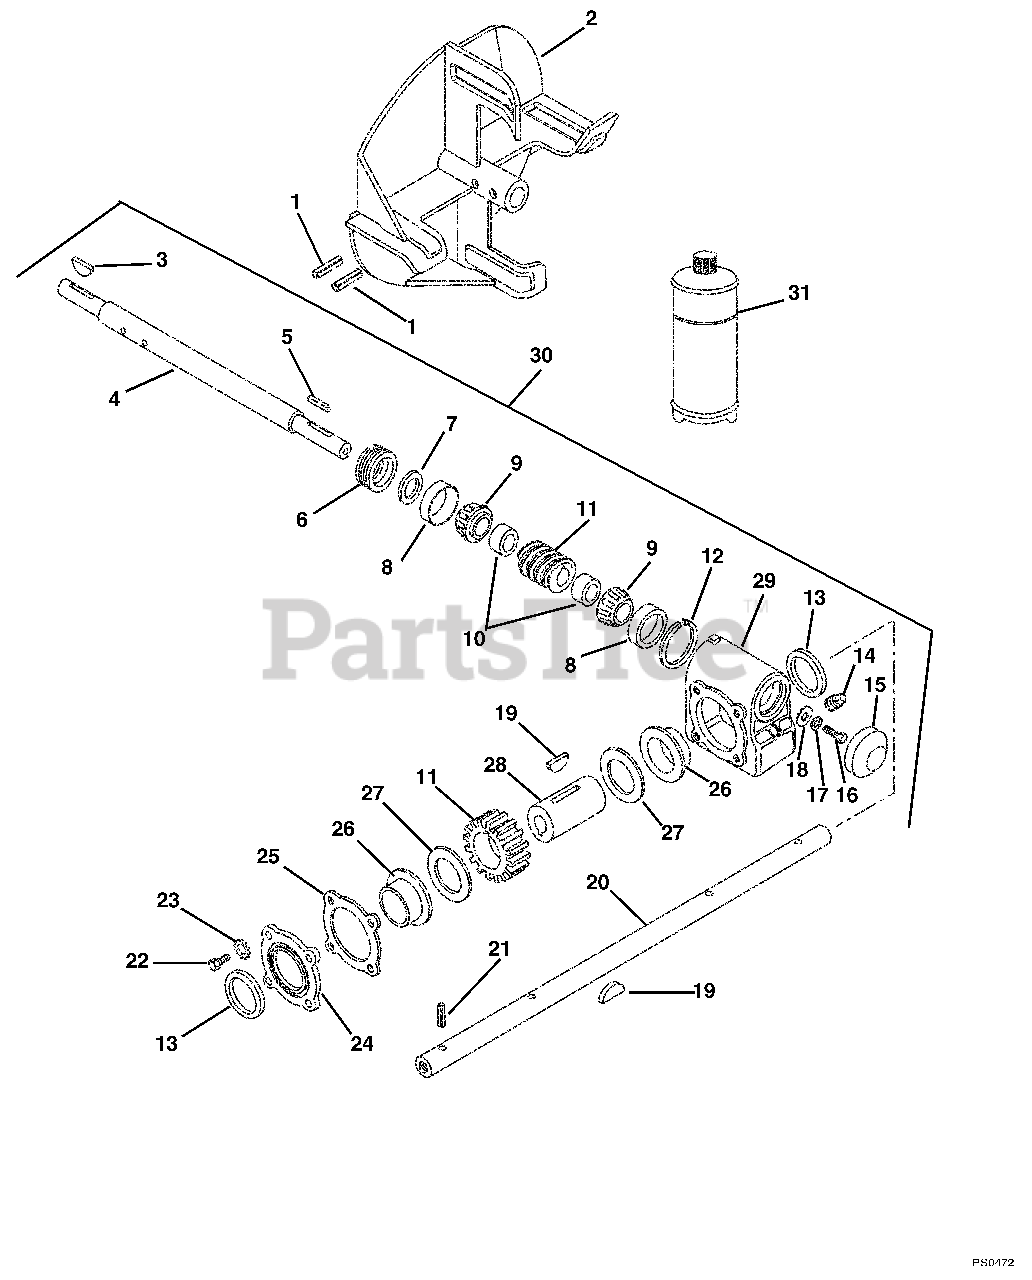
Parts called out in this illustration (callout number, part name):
1	PIN-ROLL .313X1.75
2	FAN - 14", BLACK
2	FAN, 12" BLACK
3	KEY-WDRF .188X.875X.375 SAE11
4	SHAFT, WORM - 1.00 DIA.
5	KEY-SQ .188X1.0X.188 SAE 8630
6	ADJUSTMENT PLUG - 1" SHAFT
7	SEAL 1.000X1.312X.150
8	BRG-CUP 1.781X.475
9	BRG-CONE .750X.61
10	BSHG, SPCR .755X1.12X.50 PM
11	WORM & GEAR SERVICE ASSEMBLY
12	RG-RTNG-INT 1.781X.062
13	SEAL 1.625X2.125X.250
14	PIPE PLUG
15	DUST CAP
16	@BLT-HEX .31-18X.75 GR5 YWZC
17	WSHR-LK .312X.097 HVY YWZC
18	WSHR-FL-STL .328X1.0X.094 YWZC
19	KEY-WDRF .25X.875X.375 SAE A
20	SHAFT, 24" RAKE - 1.00 DIA.
20	SHAFT, 28" RAKE - 1.00 DIA.
20	SHAFT, 32" RAKE - 1.00 DIA.
20	SHAFT, 36" RAKE - 1.00 DIA.
21	PIN-ROLL .188X1.50
22	@BLT-HEX .25-20X.75 GR5 YWZC
23	@WSHR-LK-EXT.262X.502X.026YWZC
24	GEAR CASE COVER
26	BSHG-FLG .683X1.87X1.68X2.250
27	WSHR-FL-STL 1.625X2.500X.012
28	GEAR CASE SHAFT
29	GEAR CASE - CAST IRON
30	GEAR CASE, CAST IRON
30	GEAR CASE - CAST IRON
31	ARIENS 16 OZ.BOTTLE OF L2 LUBE
